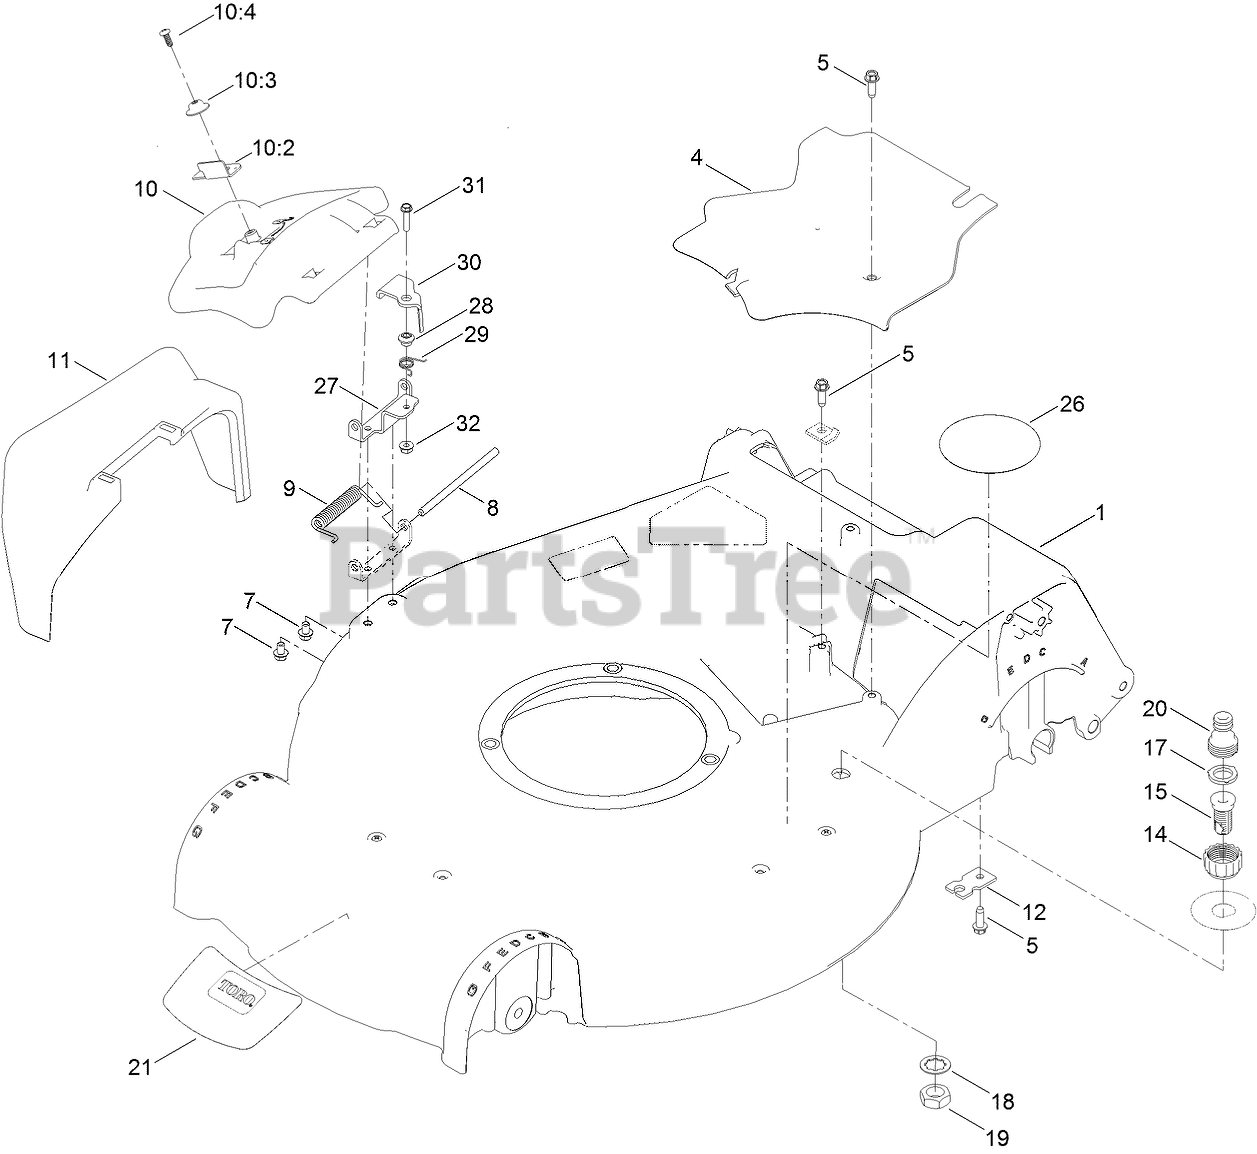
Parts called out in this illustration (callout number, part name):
1	HOUSING ASM
4	COVER-BELT
5	SCREW-HWHTF
9	SPRING-TORSION
10	DISCHARGE DOOR ASM
10:2	LATCH-DOOR
10:3	CAP-DOOR
10:4	SCREW-PPH
11	CHUTE-DISCHARGE, SIDE
12	BRACKET-CABLE, TRACTION
14	COUPLING-HOSE, WASHOUT PORT
15	PORT-WASHOUT
17	WASHER-SEAL, WASHOUT PORT
18	WASHER-LOCK, INT TOOTH
19	NUT-JAM
20	ADAPTER-CONNECT, QUICK
21	DECAL-DECK
26	DECAL-POS
27	BRACKET-LOCKOUT
28	SPACER
29	SPRING-TORSION
30	LEVER-LOCKOUT
31	SCREW-HWH
32	NUT-HEX FLANGE
